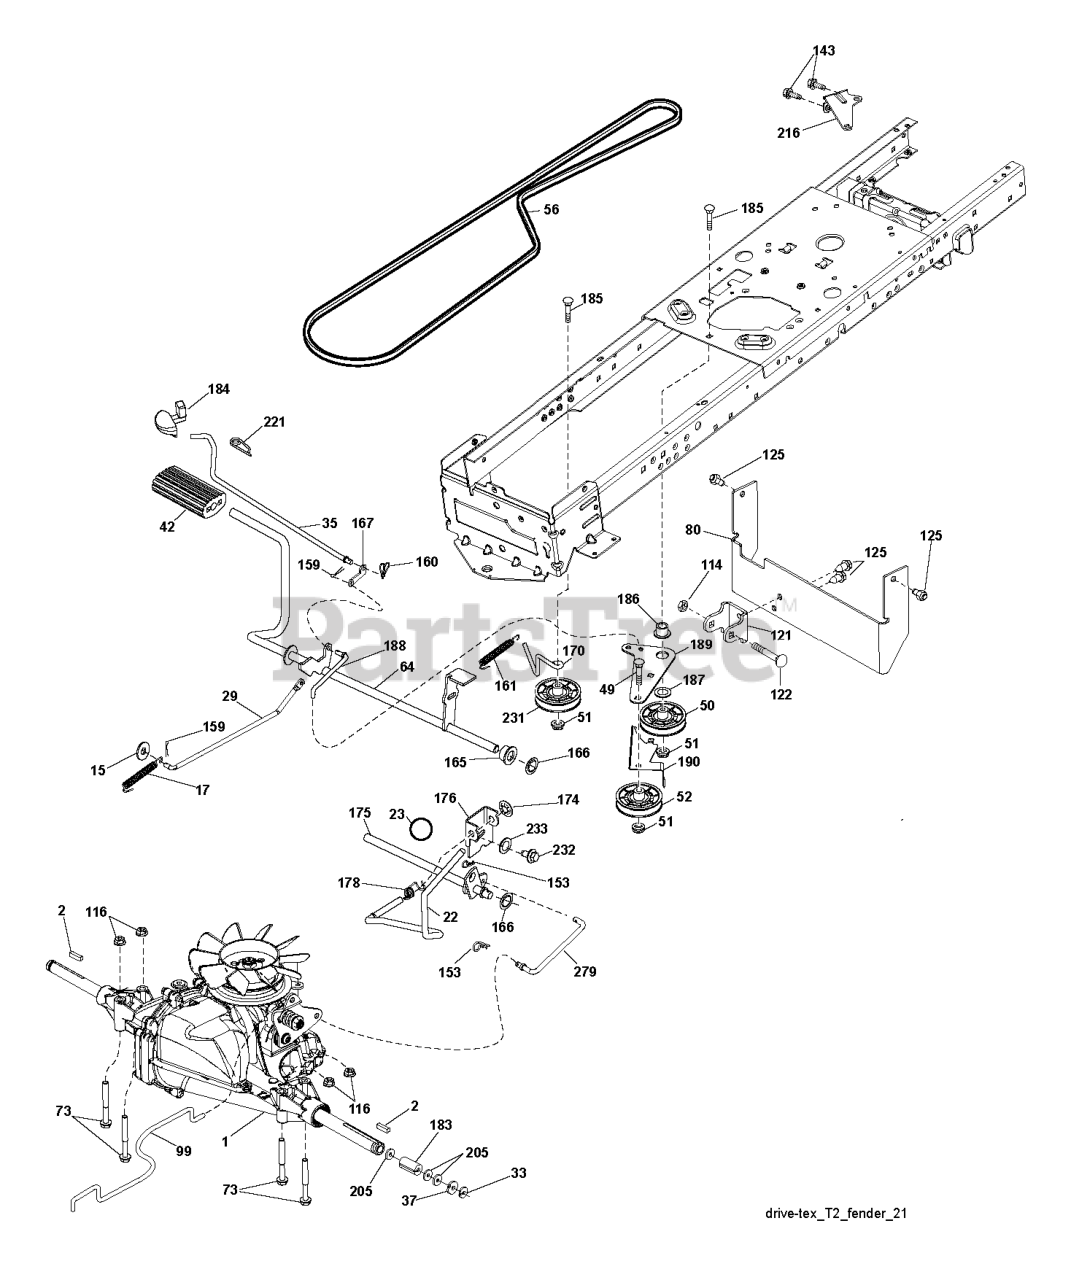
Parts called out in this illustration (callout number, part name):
2	SQUARE KEY
15	WASHER
17	SPRING.BRAKE.HG3000/3500
22	ROD.SHIFT.FENDER.TLT.2006
23	KNOB.DUCKHEAD.1/2
29	ROD.BRAKE.T2.TEX
35	ROD.CNTRL.PARK.PREDATOR.LT.TEX
42	PEDAL COVER T
50	IDLER.FLAT.910.OFFSET
51	NUT LOCK FLG 3/8-16 UNC
52	IDLER.V-GROOVE.910.OFFSET
64	SHAFT.ASM.PEDAL.BRAKE.
73	BOLT HEX 5/16-18 GR 5
80	RP.STRAP.TORQUE.FS.T2
99	ROD.ASM.BYPASS.SPRING.T2.FS
114	NUT.71038.31-18.HEX.NYLOCK
116	NUT LOCK HEX FLANGE 5/16-18
121	BRACKET STRAP TORQUE
122	BOLT.5/16-18X2.5
125	SCREW
143	Screw 5/16-18 x 1/2 Hex, Self Tapping 5/16-18 x 1/2
153	RETAINER M
159	COTTER PIN
160	RETAINER CLIP
161	SPRING, RETURN LT
165	BUSHING.SHAFT.BRAKE.HAND
166	NUT.PUSH.625
167	LATCH.BRAKE.SPRING
170	KEEPER.CENTER SPAN.1.688
174	NUT.PUSH.500.2006
175	SHAFT.ASM.SHFT.T2.TLT
176	ARM.CLEVIS.ROD.SHIFT
178	SPRING.SHIFT.GT2006
183	SPACER, AXLE PVST
184	HANDLE PARKING BRAKE
186	SPACER.RETAINER
187	WASHER 12/32X2X10GA
188	RP.LINK.CLUTCH.GROUND.DRIVE
189	BELLCRANK.GROUND.DRIVE.TEX.
190	KEEPER.BELLCRANK.DRIVE
216	BRACKET.PULLEY.IDLER.W/TEX
221	RETAINER.SPRING.CLIP.H
231	IDLER.V-GROOVE.1.688.OFFSET
232	BOLT FIN HEX 7/16-14 X 1
233	WASHER SERRATED
279	LINK.SHIFT.T2
